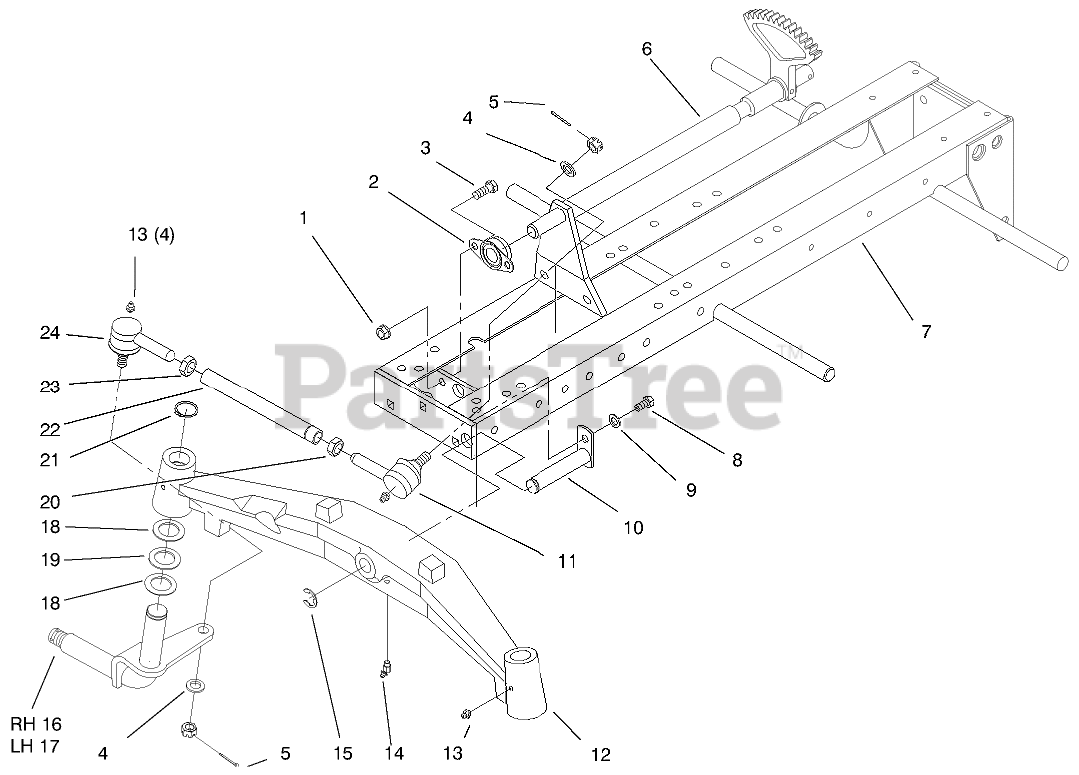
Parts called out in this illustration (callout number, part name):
1	NUT-LOCK, NI
2	BEARING-FLANGED
3	SCREW-HH
4	Spacer
5	PIN-COTTER
6	WLMT-SHFT LW (BLACK)
7	WA FRAME (RED)
8	SCREW-HH
9	WASHER-LOCK
10	PIN AND PLATE ASM
11	Balljoint-RH Thread
12	AXLE FRONT (RED)
13	FITTING-GREASE
14	FITTING-LUBE, 45 DEG
15	E-RING
16	R.H. SPINDLE WA (RED)
17	L.H. SPINDLE WA (RED)
18	WASHER-THRUST
19	BEARING-THRUST
20	NUT-JAM
21	RING-RETAINING
22	TUBE +1 (RED)
23	NUT-HEX JAM 9/16-18
24	Balljoint-LH Thread
